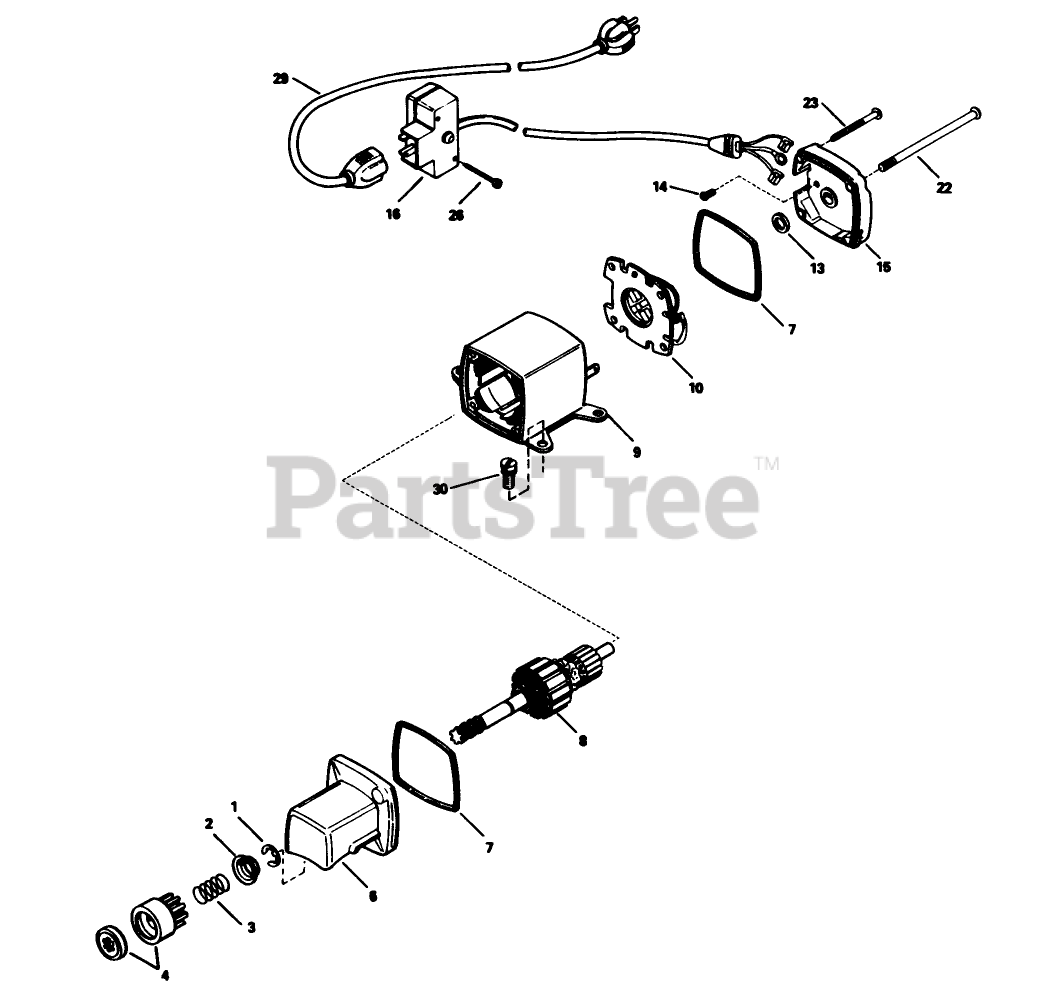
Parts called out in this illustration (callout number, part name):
1	Retainer-Ring
2	Retainer-Spring
3	Spring-Anti Drift
4	Nut Gear
6	Cap Assembly (Incl. Ref. #7)
7	O-Ring
8	Armature
9	Housing Assembly
10	Card ASM
13	Washer-Thrust
14	Screw-Ground
15	Cap Assembly (Incl. Ref. #7)
16	Box Assembly-Switch (Incl. Ref. #26)
22	Bolt-Case
23	Screw-Ground
26	Screw
29	Cord-Extension
30	Screw (T-30, 1/4-20 x 23/32)
